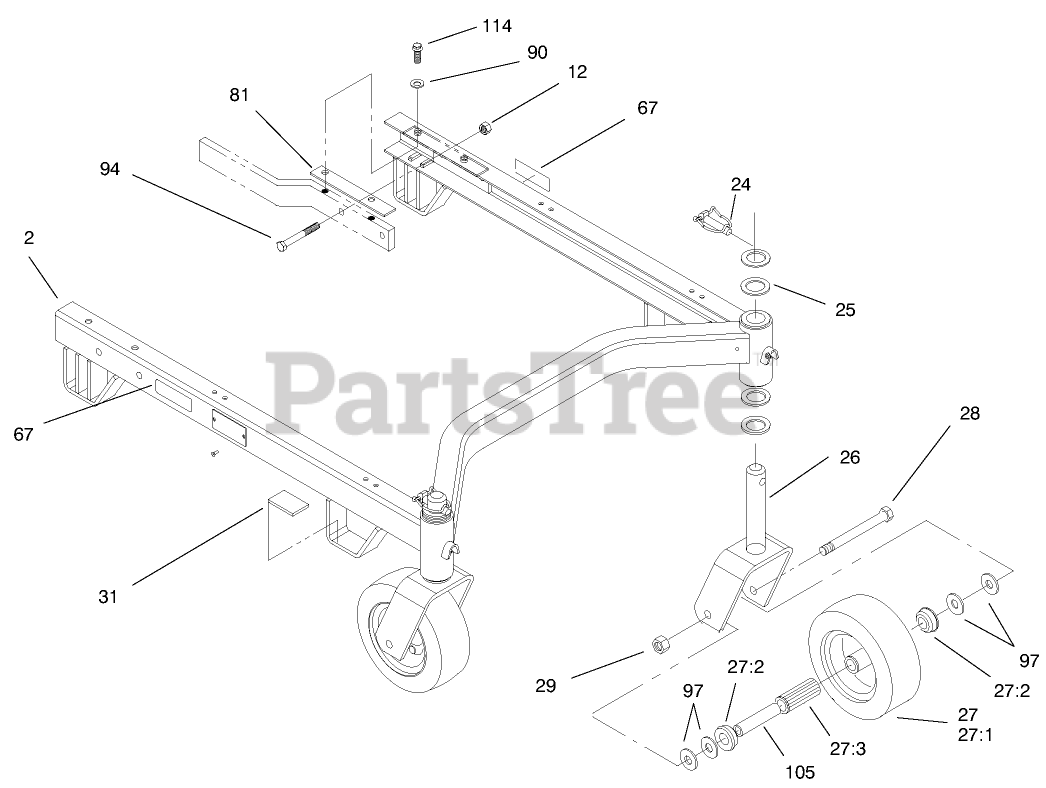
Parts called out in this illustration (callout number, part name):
2	SUSPENSION W A
12	NUT-LOCK, CONE
24	PIN-LYNCH
25	WASHER-THRUST
27	CASTOR WHEEL ASM
27:1	TIRE-TUBELESS
27:2	BEARING-OUTSIDE
27:3	BEARING-ROLLER
28	SCREW-HH
29	NUT-HEX
31	CUSHION-RUBBER
67	DECAL-HOC
81	SHIM-CARRIER
90	WASHER-FLAT
94	SCREW-HH
97	WASHER-FLAT
105	SPANNER-TIRE
114	SCREW-HHF
